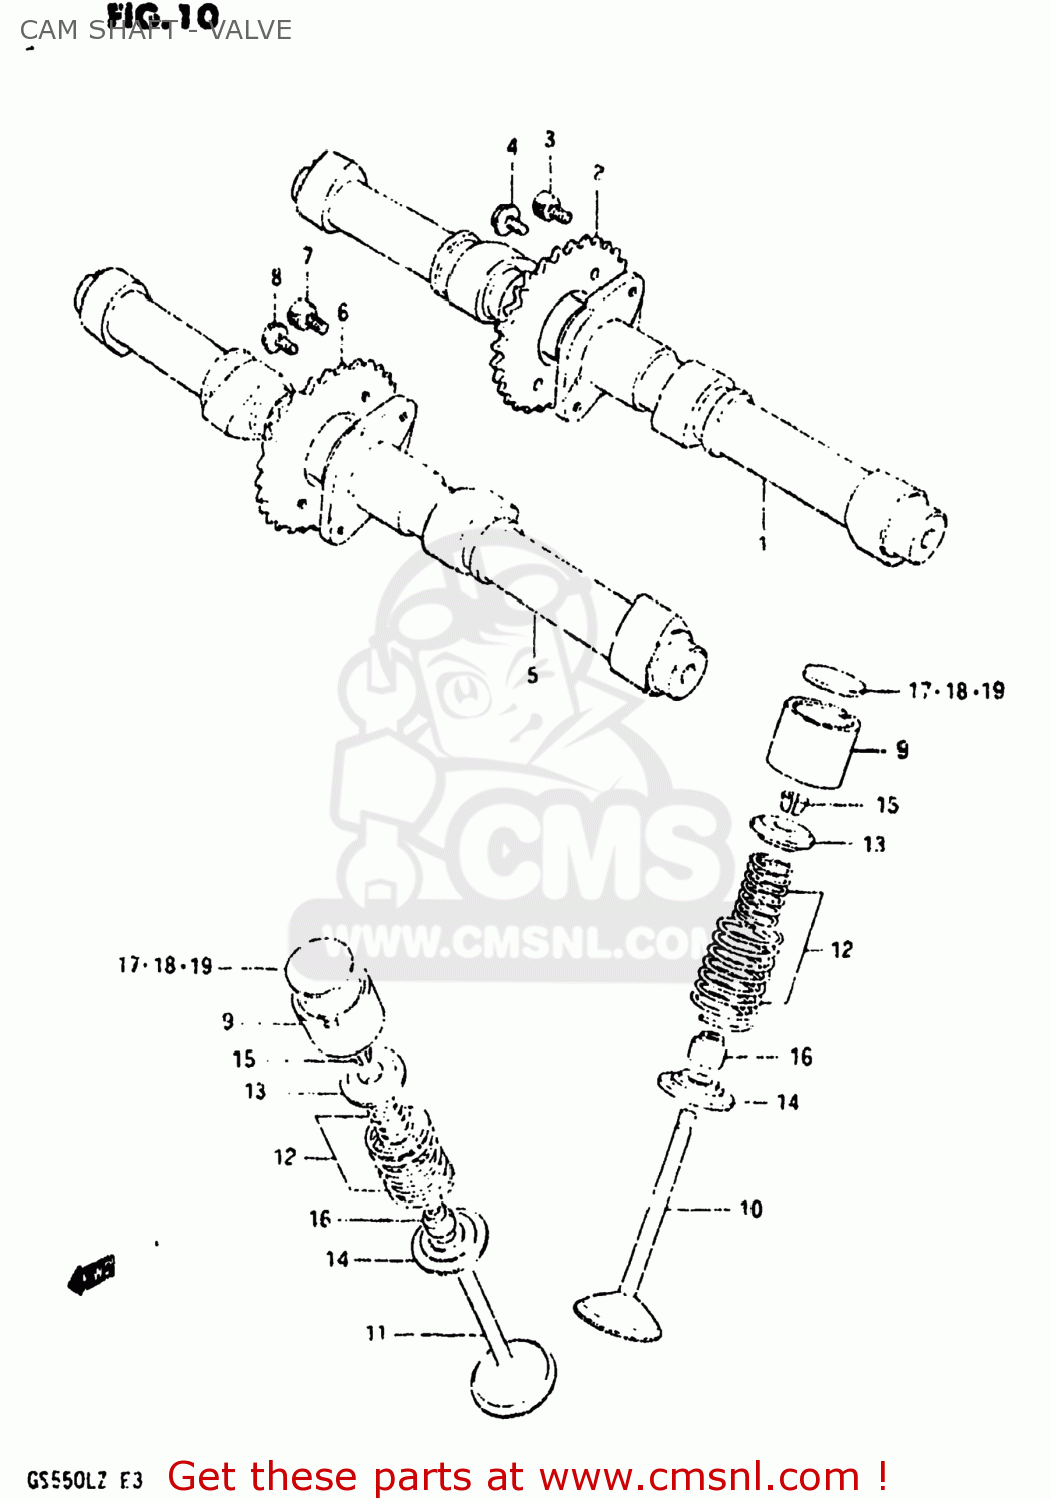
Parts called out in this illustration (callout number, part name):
1	CAMSHAFT
2	SPROCKET,CAMSHAFT
3	BOLT 6X11
4	BOLT(7X11)
5	CAMSHAFT,EXHAUST
6	SPROCKET,EXHAUST CAMSHAFT
7	BOLT 6X11
8	BOLT(7X11)
9	TAPPET
10	VALVE,INTAKE
11	VALVE,EXHAUST
12	SPRING SET,VALVE
13	RETAINER,VALVE SPRING
14	SEAT,VALVE SPRING
15	COTTER VALVE
16	SEAL,OIL(7X14.4X9)
17	SHIM,TAPPET
18	SHIM,TAPPET
19	SHIM,TAPPET
20	SHIM SET,TAPPET
21	CASE
